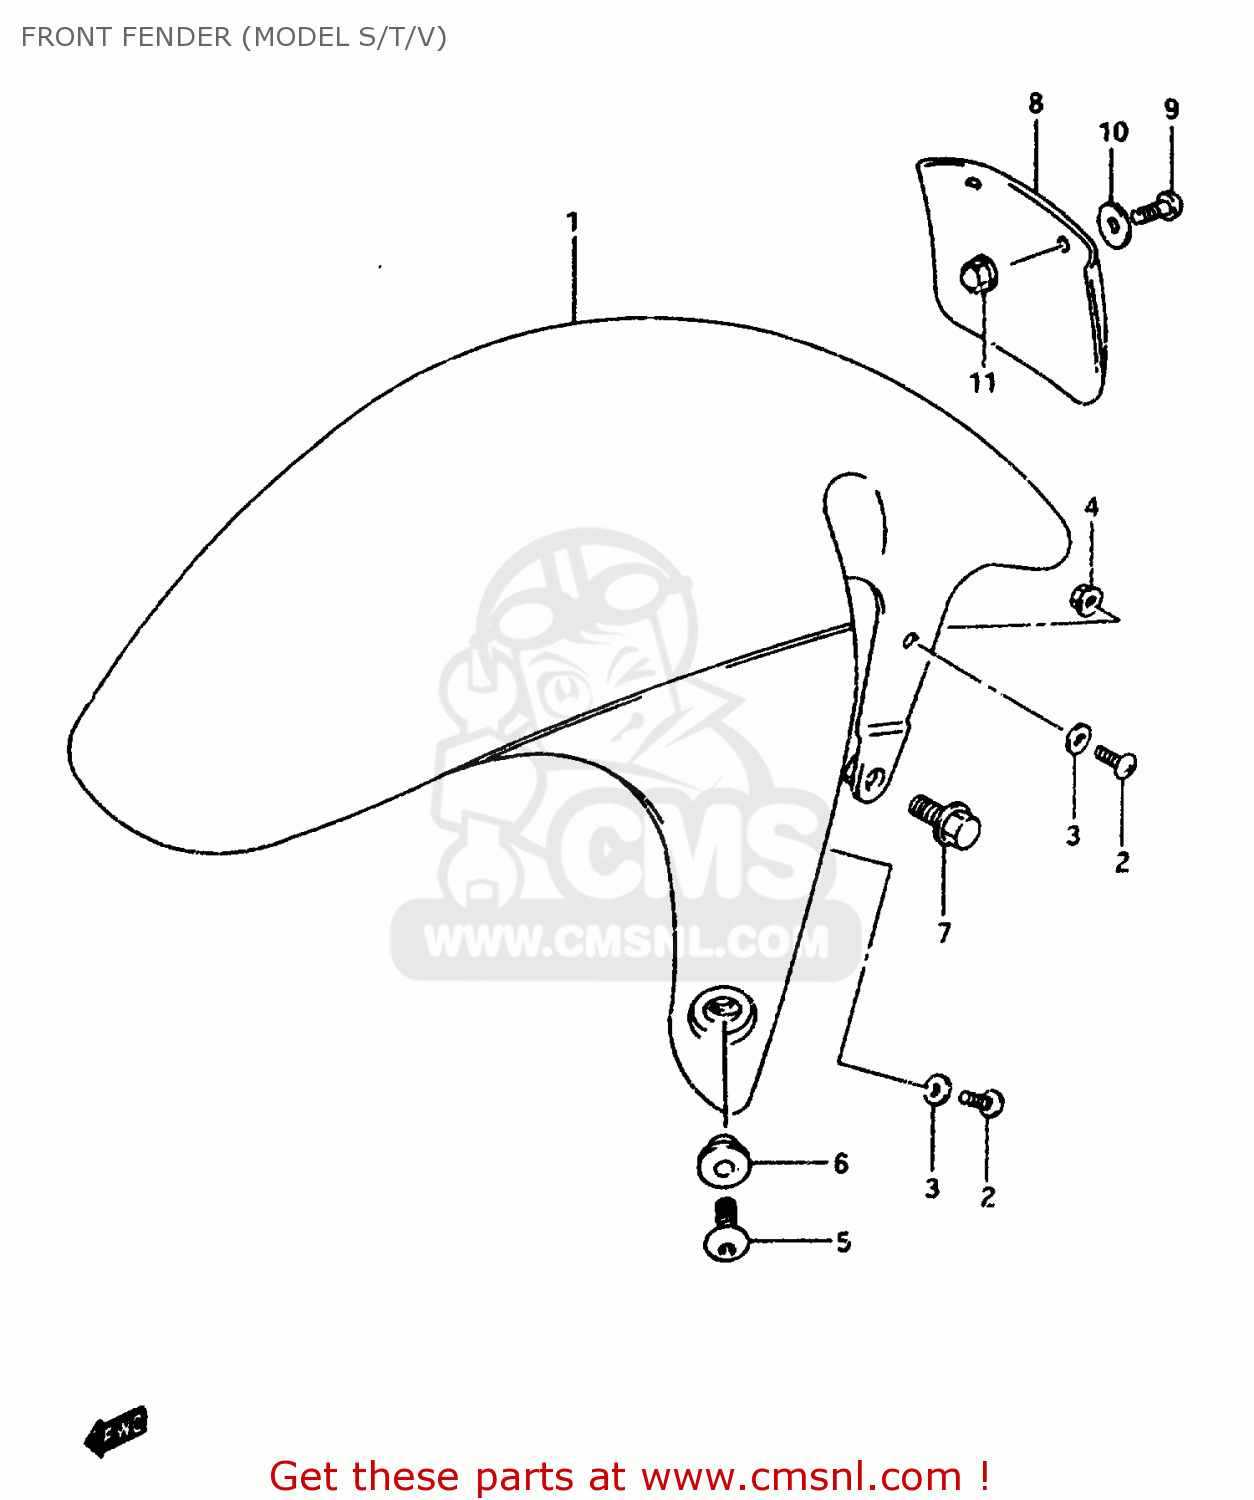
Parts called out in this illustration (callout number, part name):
1	FENDER,FR
2	SCREW
3	WASHER
4	NUT
5	SCREW(6X16)
6	WASHER(6.3X16X1.5)
7	BOLT
8	MUD GUARD,FR.F
9	SCREW 5X12
10	WASHER(5.5X20X1.2)
11	NUT
